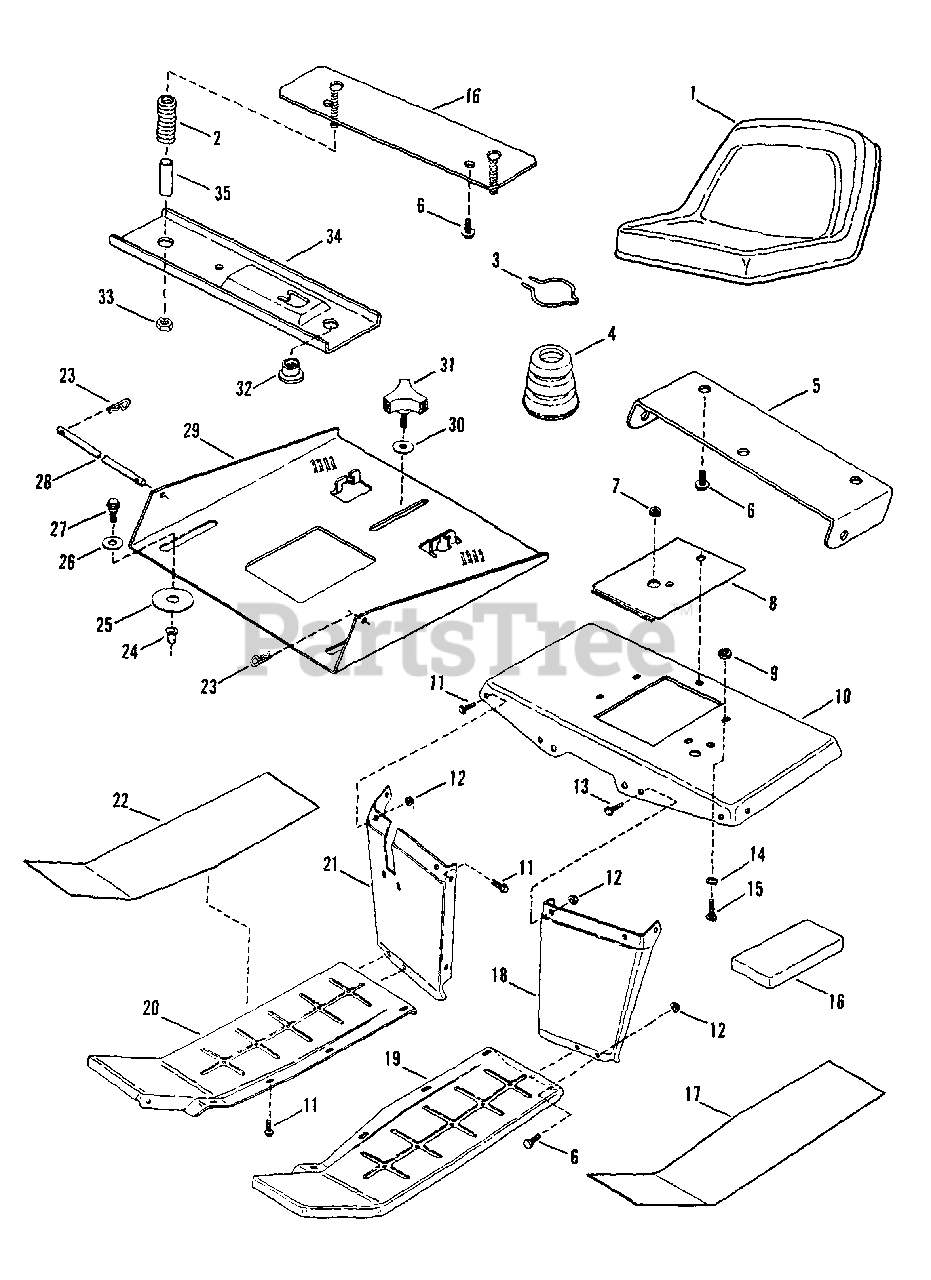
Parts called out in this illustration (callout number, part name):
1	SEAT, Operator's
2	SPRING, Seat Switch
3	CLIP, Seat Cushion
4	CUSHION, Seat
5	BRACKET, Seat Support
6	BOLT, 5/16-18 x 1/2" Hex Flange Lock
7	GROMMET, Split
8	COVER, Access
9	WASHER, 5/16
10	FENDER, Rear
11	SCREW, 5/16-18 x 5/8" Self-Tapping
12	NUT, 5/16-18 Hex Flange Lock
13	BOLT, 5/16-18 x 1/2" Short Neck Carriage
14	RETAINER, Bolt
15	BOLT, 5/16-18 x 1" Carriage
16	ADAPTER, Seat
17	TREAD, Left Side
18	EXTENSION, Fender, Left Side
19	PANEL, Step, Left Side
20	PANEL, Step, Right Side
21	EXTENSION, Fender, Right Side
22	TREAD, Right Side
23	PIN, Hair
24	RIV-NUT, 5/16-18
25	SPACER
27	SCREW, 5/16-18 x 3/4" Shoulder
28	ROD, Seat Hinge
29	SUPPORT, Seat
30	WASHER
31	KNOB, Seat Adjustment
32	BUSHING, Seat
33	NUT, 5/16-18 Hex Lock
34	HOLDER, Seat Switch
35	SPACER, Seat
